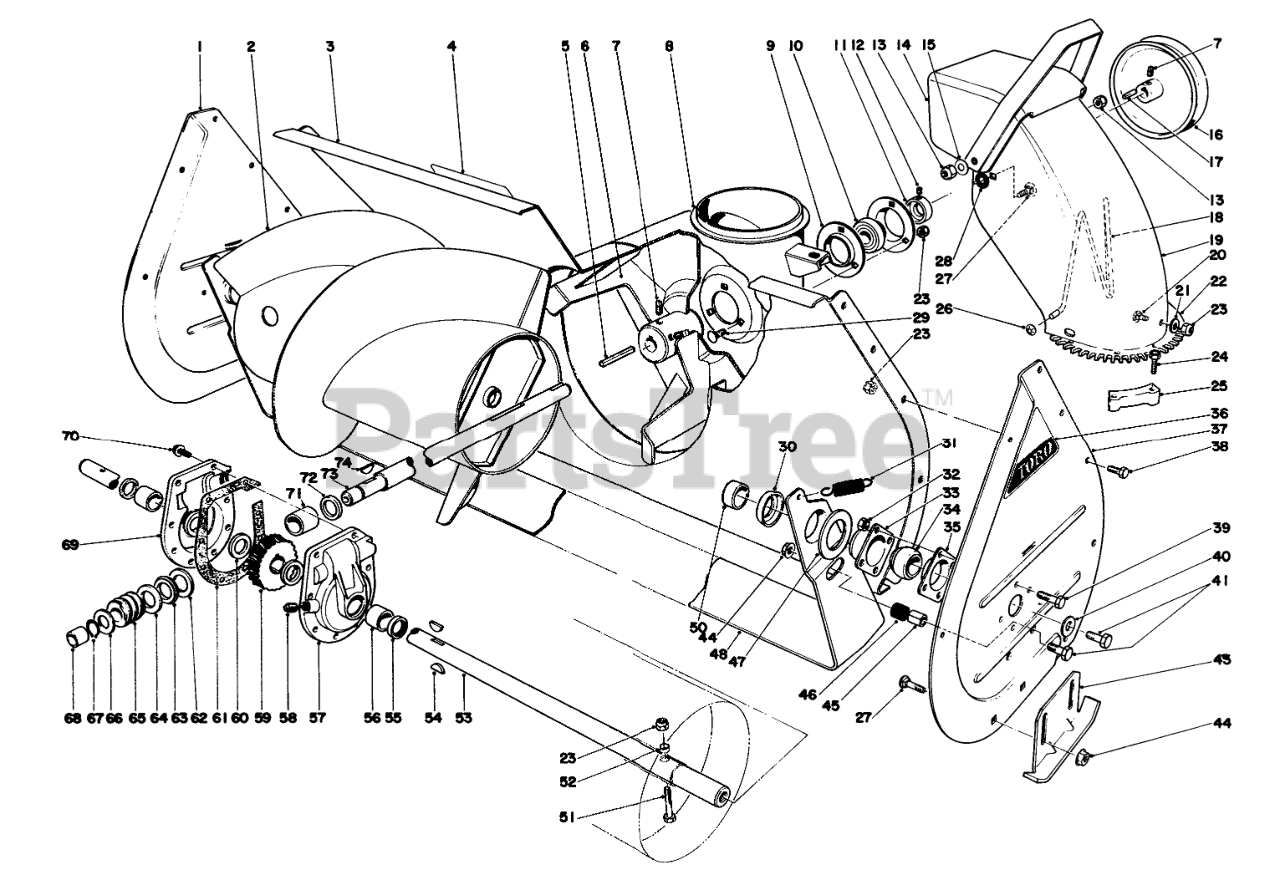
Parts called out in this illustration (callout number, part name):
1	RH AUGER SIDE PLT R
2	LH AUGER WA 32" B
3	AUGER HSG WA 32" R
4	Decal-Warning
6	IMPELLER ASM
7	Set Screw
8	CHUTE RING
9	BRG FLANGE
10	BALL BRG W/COLLAR
11	EXT LOCKING COLLAR
12	SCREW-HSH
13	NUT-LOCK, CONE
14	Deflector
15	WASHER-BELLEVILLE
16	1/2 X 9.5 DIA PULLEY
17	SQUARE KEY
18	WIRE-CHUTE
19	Upper Chute
20	SCREW-CARR
21	WASHER-PLAIN
22	Screw
23	NUT-LOCK, NI
24	SCREW-SPECIAL
25	RETAINER-CHUTE
26	NUT-PUSH
27	SCREW-CARR
28	Rubber Washer
29	BOLT-CARR
30	Positioner-Scraper
31	SPRING-TENSION
33	BEARING-FLANGE, FRONT
34	BEARING
35	BEARING-FLANGE, REAR
36	AUGER SIDE PLT DECAL
37	LH AUGER SIDE PLT R
38	SCREW-HH
39	SCREW-HH
40	WASHER
41	SCREW-HH
43	AUGER SKID WA R
44	NUT-HF
45	SCRAPER STOP SPACER
46	SCRAPER STOP CUSHION
47	SCRAPER BLADE SPACER
48	SCRAPER BLADE 32" R
50	AUGER SPACER
51	Auger Bolt
52	SPACER-HUB, AUGER
53	32 AUGER SHAFT
54	KEY-WOODRUFF
55	SEAL-OIL
56	BUSHING
57	Gear Case L.H. (Incl. Ref . #55-56)
58	PLUG-PIPE, SQH
59	GEAR-WORM, 27T
60	WASHER-THRUST
61	GASKET-CASE, GEAR
62	WASHER-THRUST
63	BEARING-THRUST
64	THRUST-WASHER
66	WASHER-THRUST
67	Ring-Snap
68	BUSHING
69	Gear Case R.H. (Incl . Ref . #55-56)
70	SCREW-TAPTITE
71	BUSHING-SPECIAL
72	RING-QUAD
73	SHAFT-IMPELLER
74	KEY-WOODRUFF
